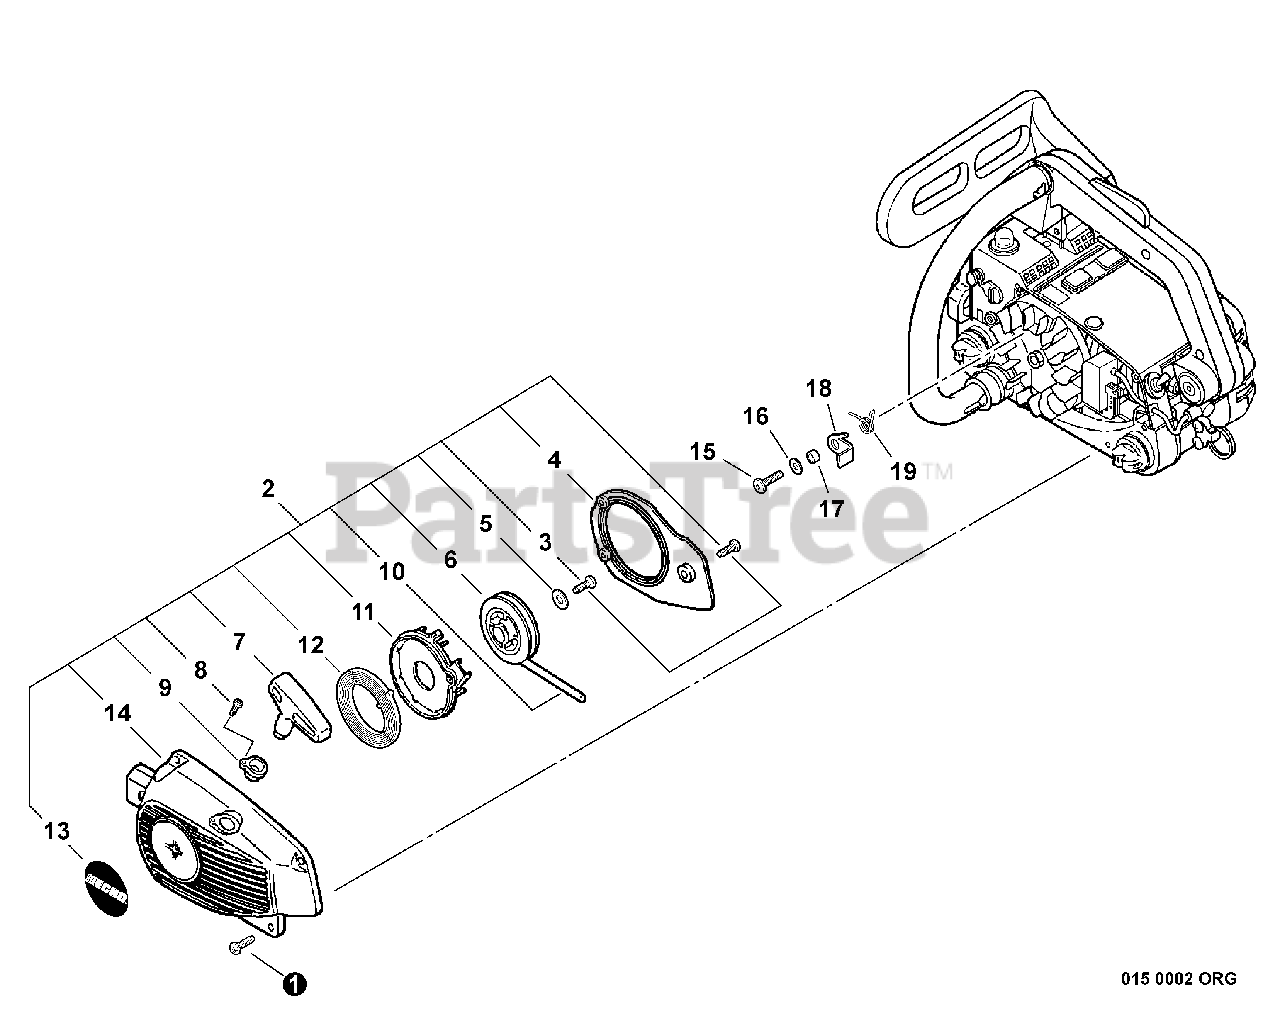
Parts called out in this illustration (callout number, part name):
1	SCREW 4×16
2	STARTER ASSY
3	SCREW 4×14
5	WASHER 4.1×15.5×1T
6	REEL, ROPE
7	GRIP, STARTER
8	SCREW 3×14
9	GUIDE, ROPE
10	ROPE, STARTER 3.0×850
11	PLATE, STARTER
12	SPRING, RECOIL
13	LABEL, ECHO
14	CASE, STARTER
15	SCREW 5×12
16	WASHER 5.5×12×0.8
17	SPACER 5.2×8×2.1
18	PAWL, STARTER
19	SPRING, TORSION
